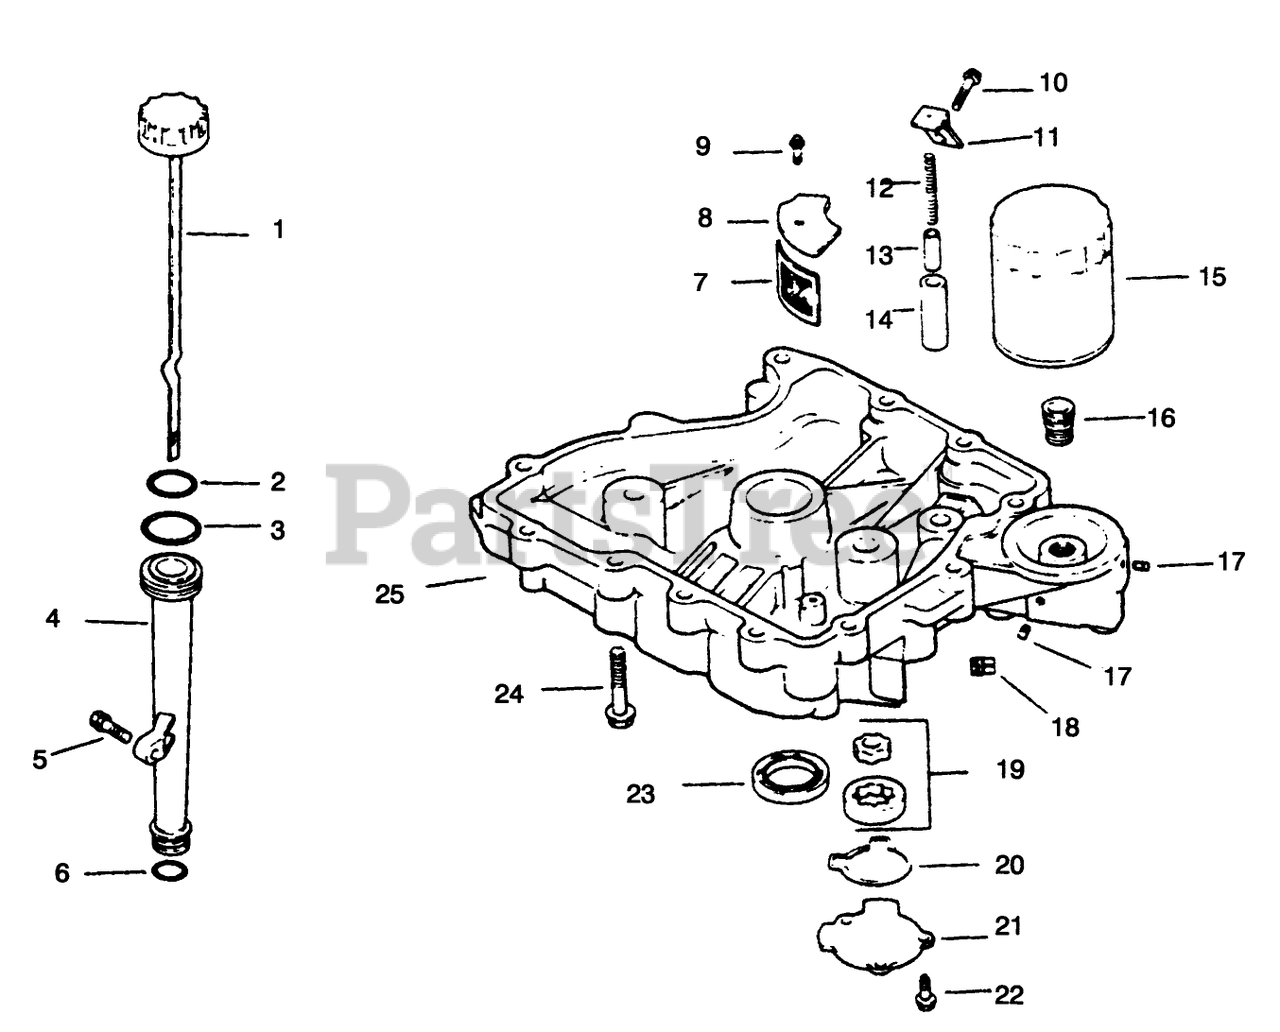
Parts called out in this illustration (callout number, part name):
1	Dipstick INC 2-3 (Only On: 72042, 72063, 72062, 72043)
2	ORing
3	O Ring-Upper Fill Tube (Only On: 72103)
4	Tube-Oil Fill (Only On: 72103, 72083)
6	O-Ring-Lower Fill Tube (Only On: 72042, 72063, 72062, 72043)
7	Screen-Oil Pickup (Only On: 72042, 72063, 72062, 72043)
8	Cover-Oil Pickup Screen (Only On: 72042, 72063, 72062, 72043)
11	Bracket-Oil Pump Relief (Only On: 72042,72043,72062,72063)
12	Spring-Oil Relief Valve (Only On: 72042,72043,72062,72063)
13	Piston-Oil Relief Valve (Only On: 72042, 72063, 72062, 72043)
14	Body-Oil Relief Valve (Only On: 72042, 72063, 72062, 72043)
15	Filter-Oil
16	Adapter-Oil Filler
17	Plug-SH 1/8
19	Pump-Oil (Only On: 72042, 72063, 72062, 72043)
20	O Ring-Oil Pump Cover (Only On: 72042,72043,72062,72063)
21	Cover-Oil Pump (Only On: 72042,72043,72062,72063)
23	Seal-Crankshaft (Only On: 72042, 72043, 72062, 72063)
25	Pan-Oil
